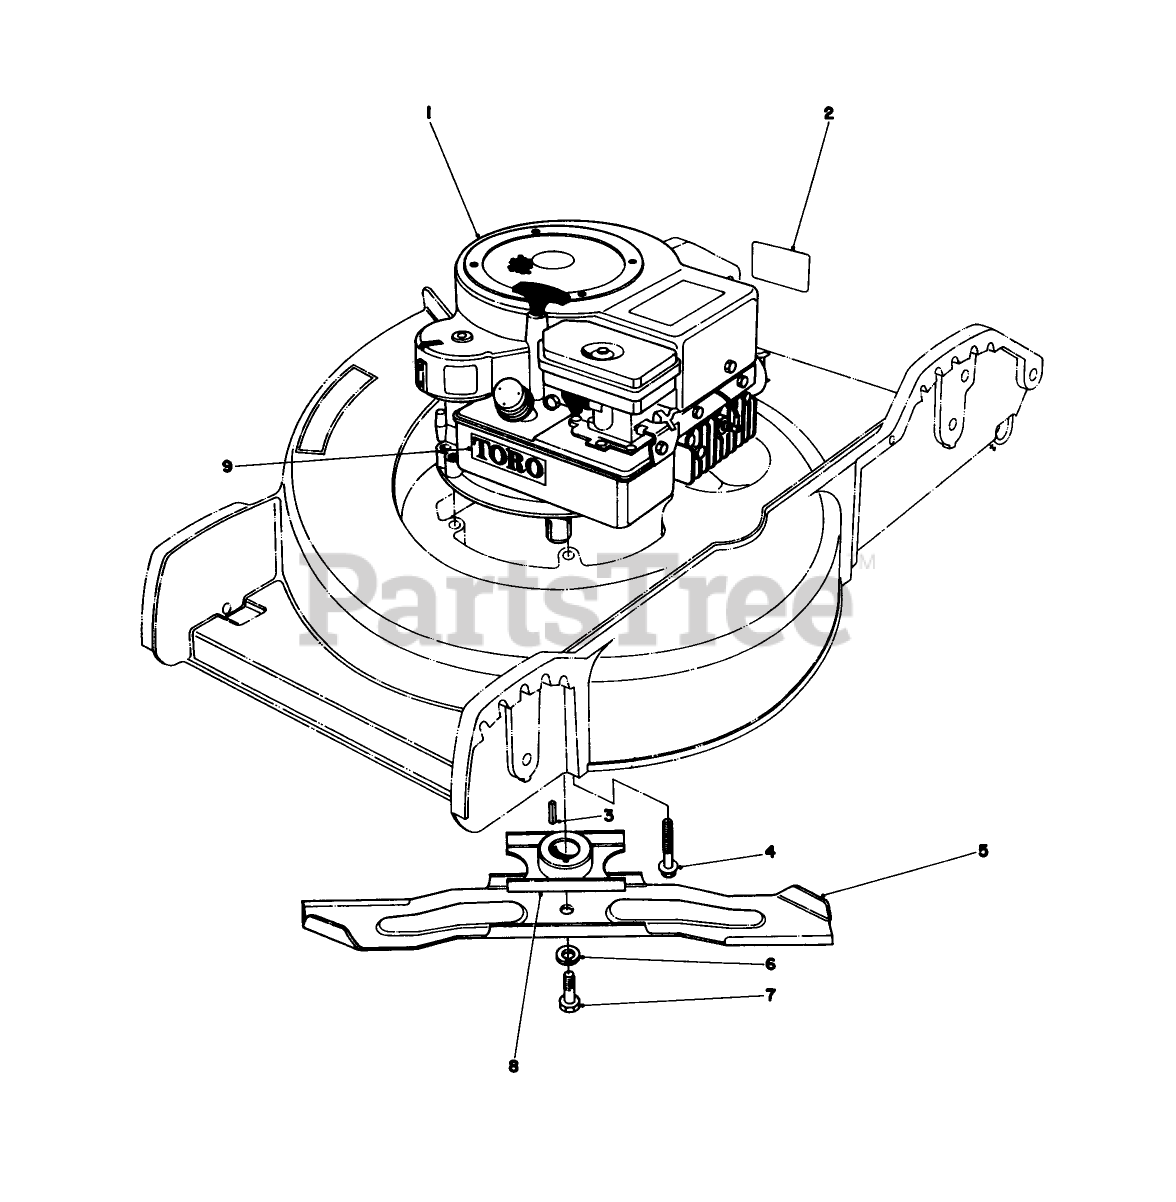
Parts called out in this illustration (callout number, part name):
1	Engine
2	Decal Maintenance
3	KEY-SQUARE
4	3/8-16 X 2 CAPSCREW
5	Blade
6	WASHER-LOCK
7	SPECIAL SCREW
8	Blade Retailer
9	Decal Toro
